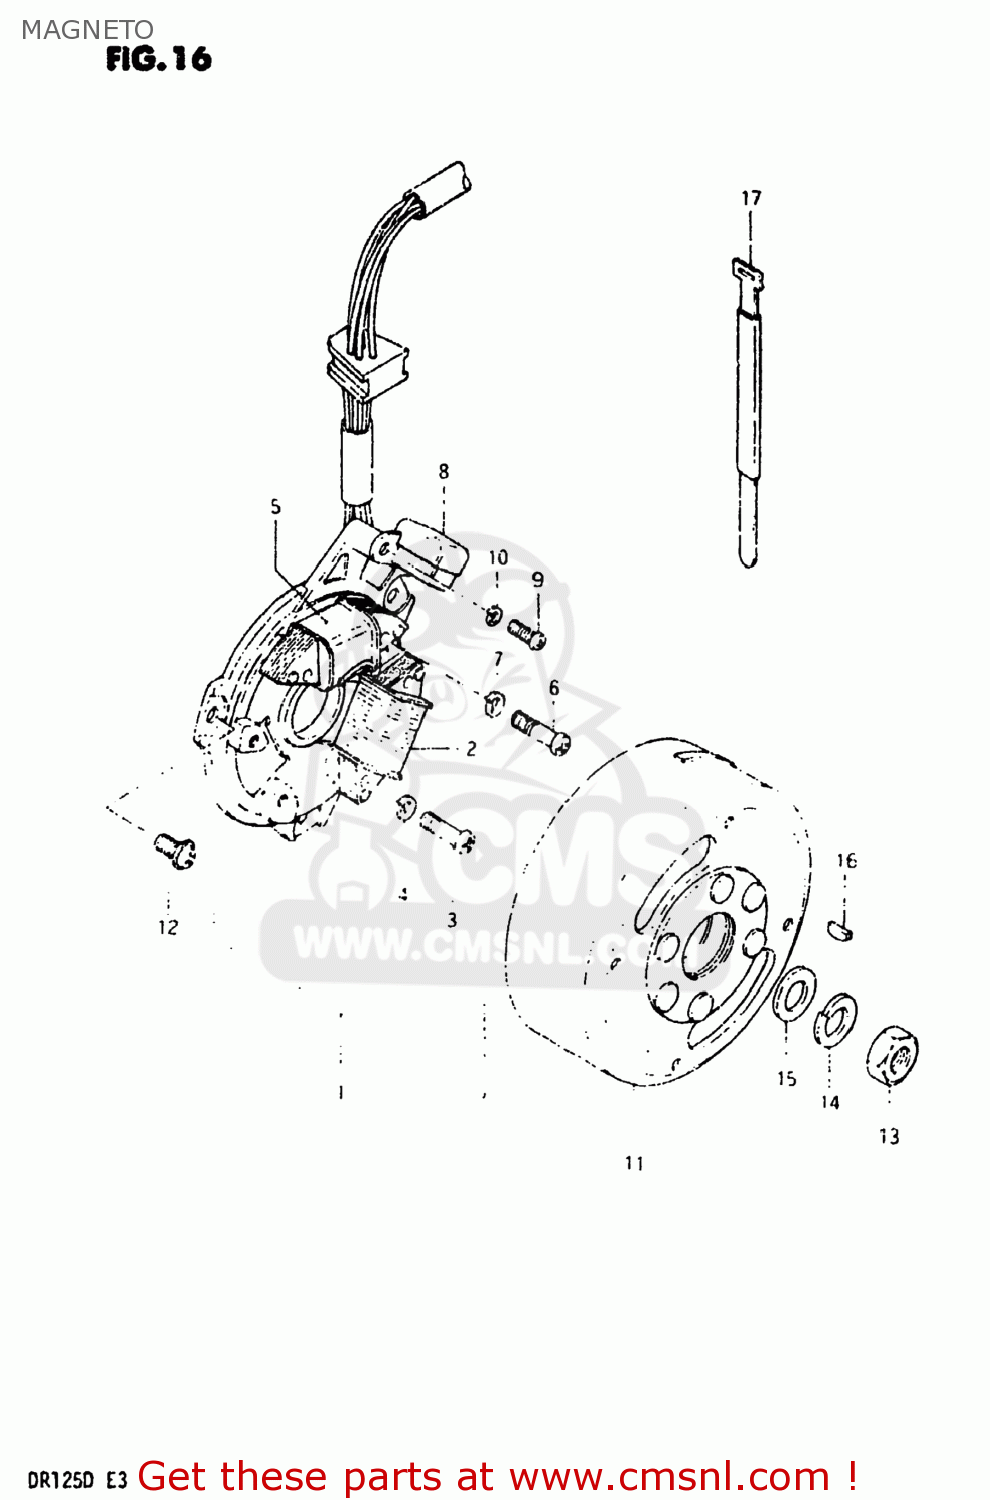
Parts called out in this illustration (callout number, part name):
1	STARTER ASSY
2	COIL,LIGHTING
3	SCREW
4	LOCK WASHER
5	COIL,IGNITION PRIMARY
6	SCREW
7	LOCK WASHER
8	COIL
9	SCREW
10	LOCK WASHER
11	ROTOR ASSEMBLY
12	SCREW(5X14)
13	NUT (10MM)
14	LOCK WASHER
15	WASHER
16	KEY
17	CLAMP L:110
